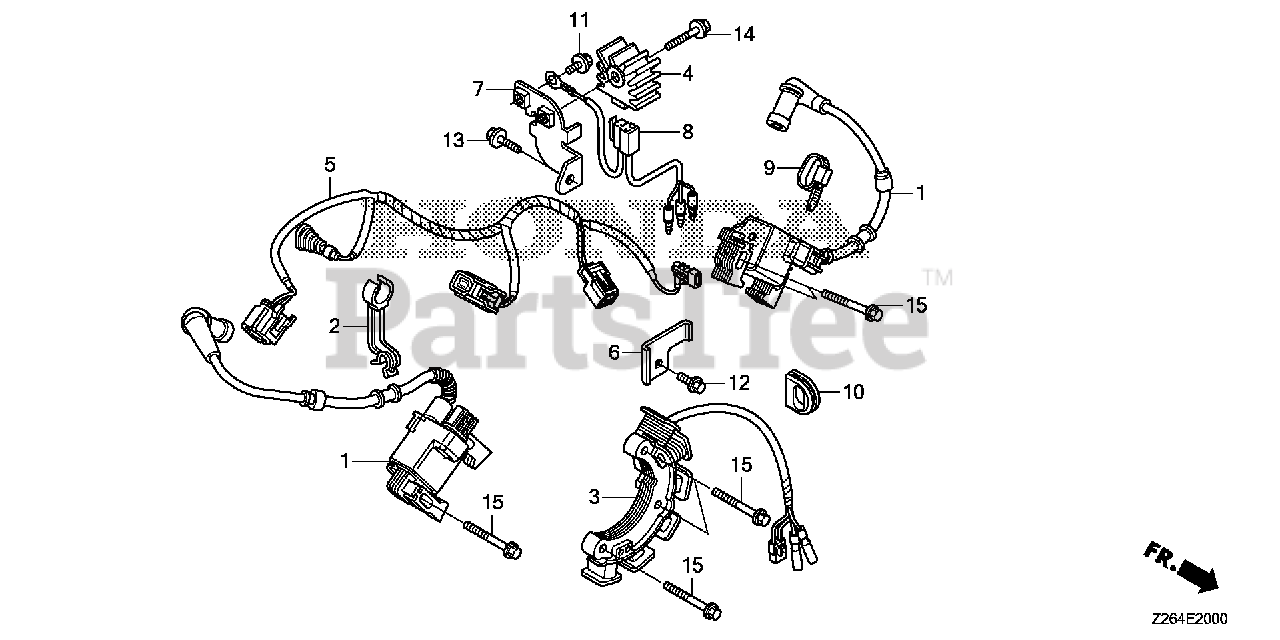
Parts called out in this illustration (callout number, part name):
1	COIL ASSY., IGNITION
2	CLAMP, IGNITION WIRE
3	COIL ASSY., CHARGE
4	RECTIFIER, REGULATOR (5A)
5	WIRE HARNESS ASSY., ENGINE
6	BRACKET, HARNESS
7	BRACKET, REGULATOR RECTIFIER
8	HARNESS ASSY., REGULATOR RECTIFIER
9	BAND, WIRE (95MM)
10	GROMMET, CORD
11	BOLT, FLANGE (6X8)
12	BOLT, FLANGE (6X12)
13	BOLT, FLANGE (6X14)
14	BOLT, FLANGE (6X30)
15	BOLT, FLANGE (6X32)
